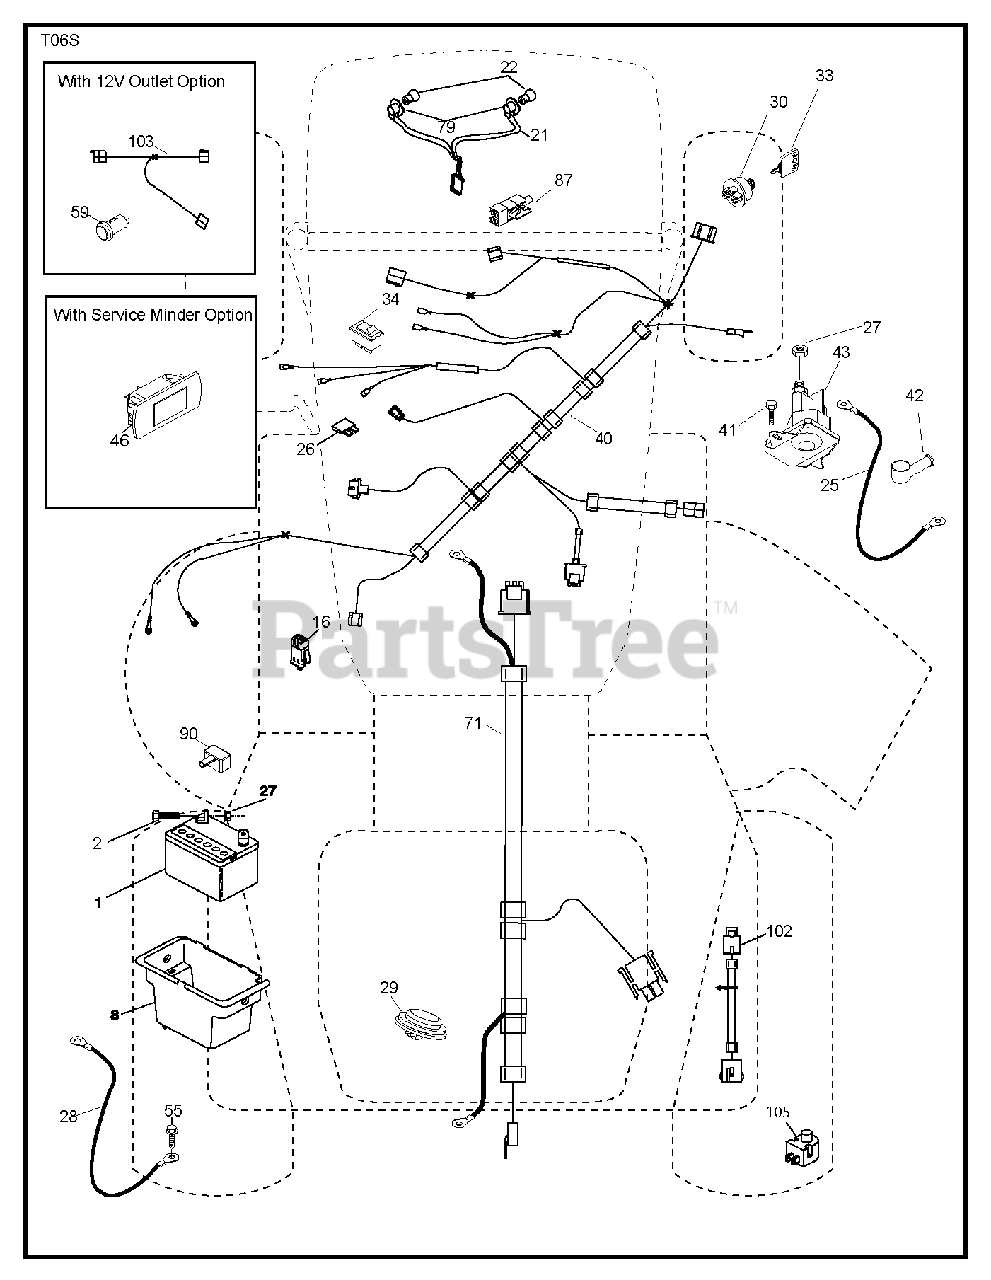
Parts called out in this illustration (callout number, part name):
1	Battery, Dry 30 Amp
2	BOLT.HEX.1/4.X.3/4.DICHROMATE
8	BOX.BATTERY.MNT.REAR.L
16	SWITCH INTERLOOK PUSH-IN
21	HARNESS ASSY LIGHT
25	CABLE.STARTER.6G.BL/RED.17.5
26	FUSE 20AMP
27	NUT
28	CABLE.BLACK.18"REAR.BA
29	SWITCH.SEAT.DELTA.OPC.
30	SWITCH.IGN.DELTA.W.LGH.ROS
33	KEY.CHAIN.BLISTER.PACK.GEN.USA
40	HARNESS IGN. DASH
41	SCREW
42	TERMINAL COVER
43	SOLENOID.W/BRASS.PLUNGER
46	RP GUAGE.SRVCMNDR.HRMTR.
55	SCREW 5/16"
71	HARNESS.IGN.CHASS.TEX.REAR.BAT
79	BULB HOLDER ASM.
87	SWITCH.INTRLCK.CLUTCH.
90	COVER, TERMINAL BATTERY
102	HARNESS PIGTAIL PCH TEX ROS
105	REVERSE SWITCH
